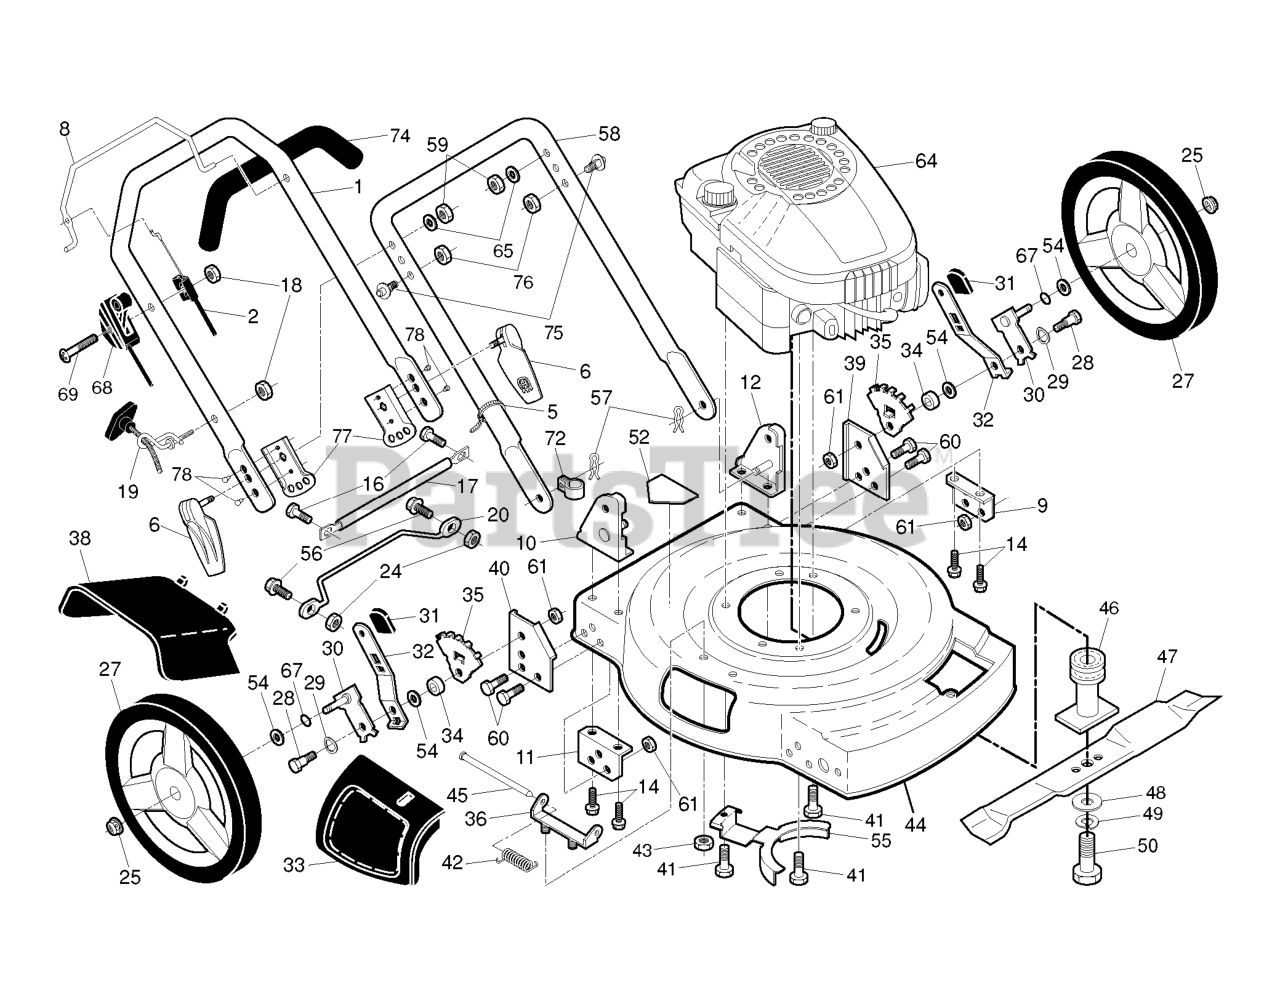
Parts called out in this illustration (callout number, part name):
1	Upper Handle
2	ENGINE ZONE CONTROL CABLE
5	TIE GUIDE
6	QUICK.ASM.RELEASE.BLACK
8	BAIL.COMF.FWGD.668.ORANGE.WALK
9	GUARD.SLKSCR.BELT.
10	Handle Bracket Assembly, RH
11	Support Bracket, Handle, RH
12	Handle Bracket Assembly, LH
14	SCREW.5/16-18X3/4
16	SCREW 14-20 X 5/8
17	SUPPORT ROD
18	NUT
19	RB GUIDE.ROPE.STD.BLK.ZIN WSL
25	NUT.HEX.FLANGE.3/8-16.LOCKNUT
27	WHEEL ASSY
28	BOLT SHOULDER 3/8 -16X1
29	WASHER.CURVED.CYLINDRICAL
30	ARM.ASM.AXLE.5/9.POS.BZP
31	SELECTOR KNOB
32	SELECTOR SPRING, FRONT
33	DOOR.MULCH.22.EZ.MULCH.GREY
34	SPACER.HEIGHT.ADJUSTER
35	BRACKET.ADJ.WHEEL.5POS.ADS
36	BRACKET.ASM.HOUSING.EZ.MUL
38	DEFLECTOR.GUARD.22..EZ.MULCH
39	BRACKET.SUPPORT.LT.12.WHL.ORNG
40	BRACKET.SUPPORT.RT.12.WHL.ORNG
41	BOLT 3/8-16X1-1/8
42	TORSION SPRING
43	LOCKNUT.NYLOC.1/4-20
44	Kit, Mower Housing
45	ROD.HINGE.COMBI-C
46	ADAPTER.BLADE/PULLEY.25M
47	Blade, 22"
48	WASHER,HARDEN
49	LOCKWASHER
50	SCREW, HEX HD 3/8-24 X 1-3/8
52	DECAL.INTERNATIONL.CUTFINGER
54	WASHER.FLAT.1/2
55	BRACKET.ENG/BELTKEEPER.BZP
56	REPL BY 817 02 10-08
57	HAIRPIN COTTER
58	HANDLE LOWER EZ 2POS GRAY
59	Locknut, Hex 1/4-20
61	LOCKNUT
65	WASHER.20X8.5
67	O-RING..070X.487.NEOPRENE
68	Control Throttle
72	CLIP.CABLE.BLK
74	GRIP.HANDLE.FOAM
75	STUD.QUICK.ADJUST
76	NUT.LOCK.5/16-18
77	BRACKET.ADJ.3POS.GREY
